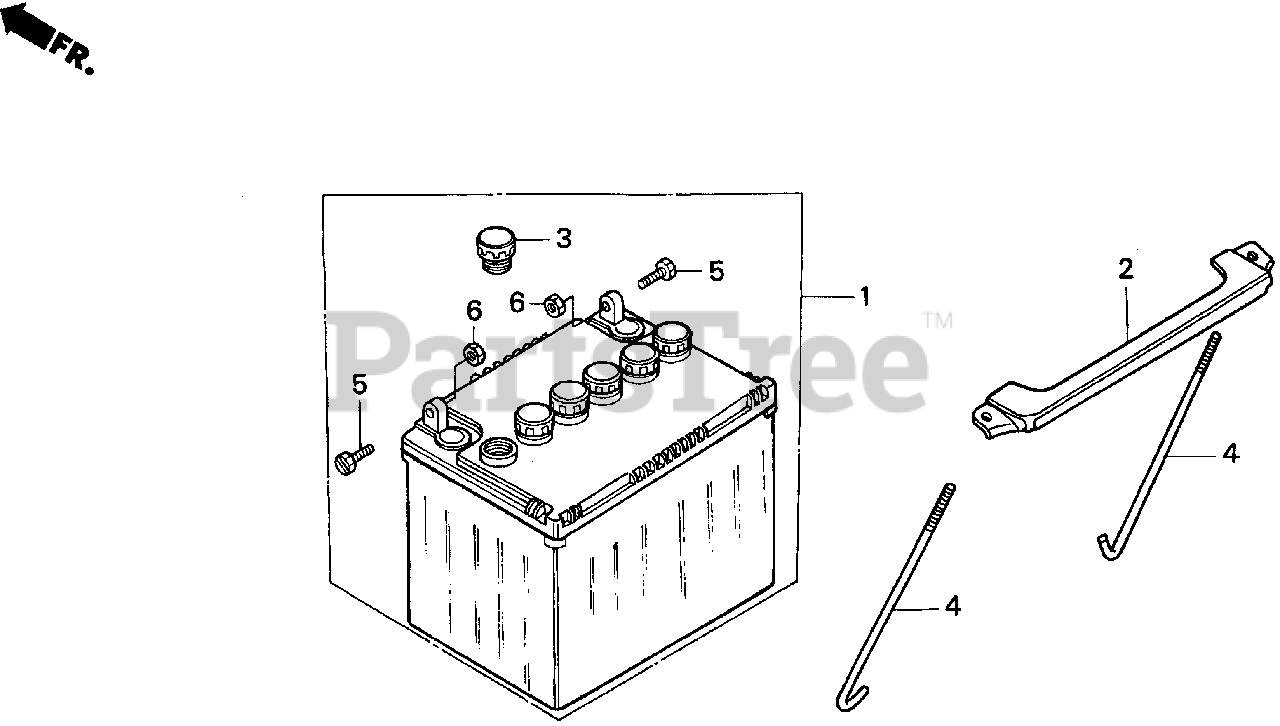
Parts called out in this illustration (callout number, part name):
1	BATTERY ASSY. (32A19L) (YUASA)
2	PLATE, BATTERY SET
3	PLUG, VENT
4	BOLT, BATTERY SETTING
5	BOLT, BATTERY TERMINAL
6	NUT, BATTERY TERMINAL
